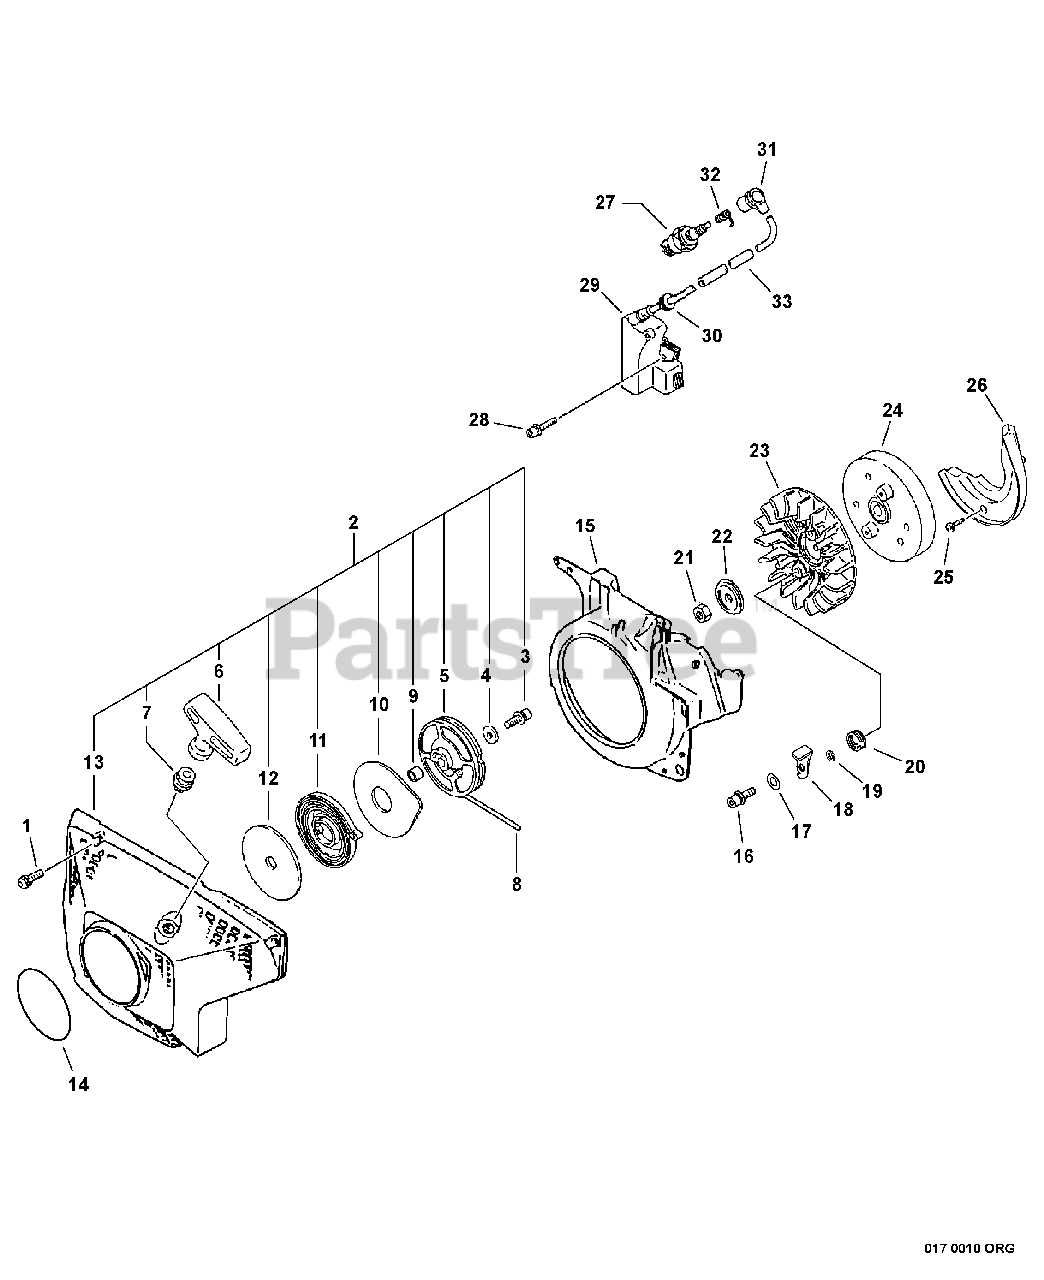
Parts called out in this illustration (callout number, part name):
1	SCREW - 5X20
2	STARTER ASSY
3	SCREW - 5X14
4	WASHER - 5
5	REEL, ROPE
6	GRIP, STARTER
7	GUIDE, ROPE
8	ROPE, STARTER - 4X950
10	PLATE, STARTER
11	SPRING, REWIND
12	PLATE, STARTER
13	CASE, STARTER
14	LABEL - ECHO
15	SHIELD, FAN
16	SCREW - 5X30
17	WASHER - 5
18	PAWL, STARTER
20	SPRING, RETURN
21	NUT - FLANGE
22	WASHER - CUP
24	FLYWHEEL
25	SCREW - 5X20
26	SHIELD, FAN
27	SPARK PLUG -- BPM-7A
28	SCREW - 4X20
29	COIL, IGNITION
31	CAP, SPARK PLUG
32	TERMINAL, SPARK PLUG CAP
